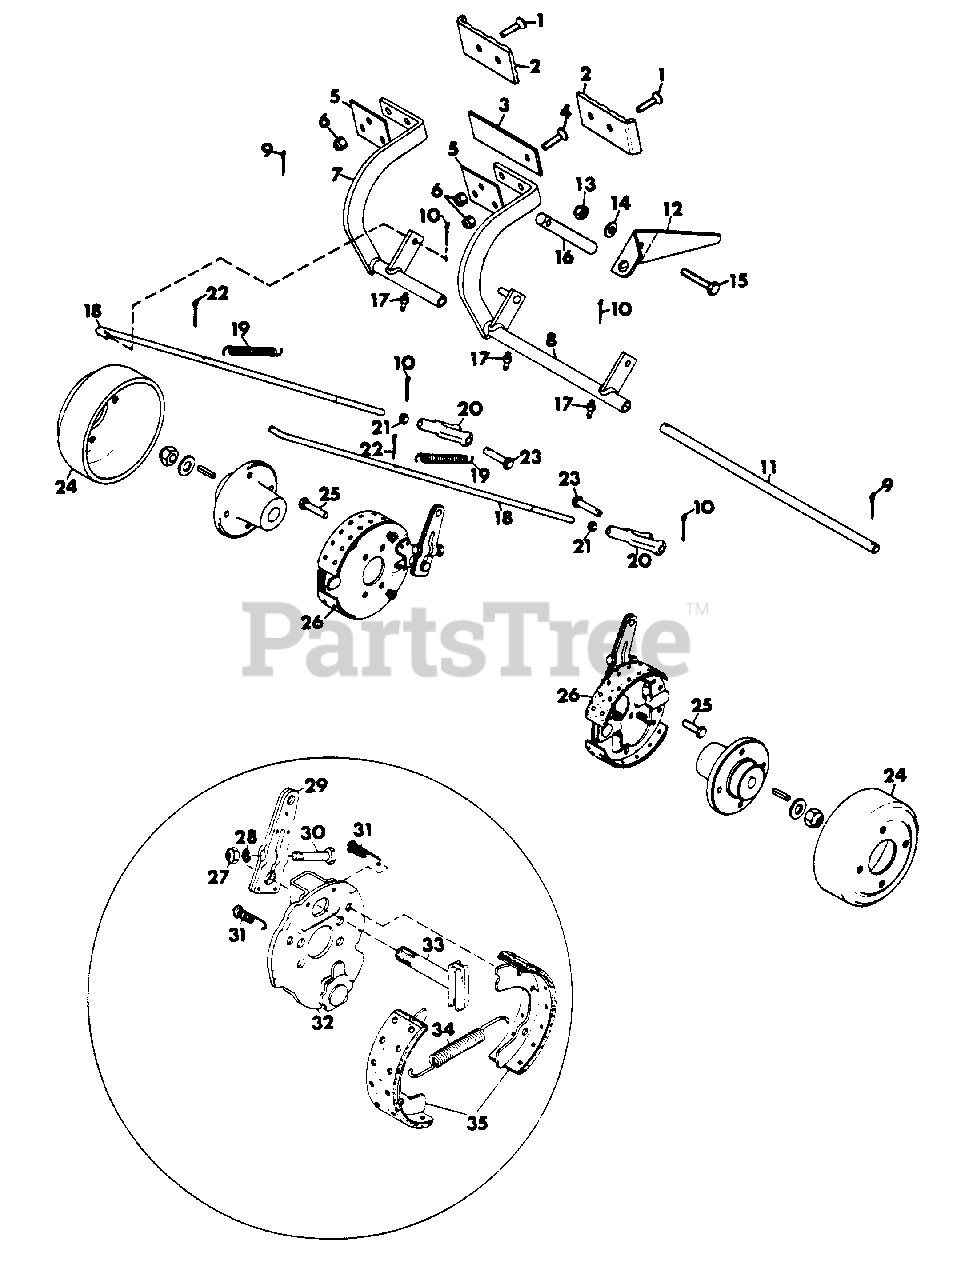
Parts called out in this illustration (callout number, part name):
1	SCREW, MACH. 1/4-20X1.25
2	PEDAL, BRAKE
3	ARM, BRAKE LOCK
4	SCREW, MACHINE 1/4-20X1.00
5	PLATE, BRAKE LOCK BACKING
6	NUT, LOCK 1/4-20
7	PEDAL, BRAKE R.H.
8	PEDAL, BRAKE L.H.
9	PIN, COTTER .125X1.25
10	PIN, COTTER .09X.75
11	SHAFT, BRAKE
12	LEVER, BRAKE LOCK
13	NUT, LOCK 3/8-16
14	WASHER, NYLON .375X.75X.060
15	BOLT, HEX 3/8-16X2.25
16	ROD
17	FITTING, LUBE 1/4-28
18	ROD, BRAKE
19	SPRING, EXT. 5.50X.50X20 RATE
20	CLEVIS, 3/8-24 ADJUSTABLE
21	NUT, JAM 3/8-24
22	PIN, COTTER .125X.750
23	PIN, CLEVIS .375X.948
24	DRUM, 7X1.75
25	BOLT, HEX 3/8-16X.75
26	BRAKE, 7X1.75
27	NUT, HEX 5/16-24
28	WASHER, LOCK 5/16
29	ARM, CAM LEVER
30	BOLT, HEX 5/16-24X1.75
31	SPRING, SHOE RETAINING
32	PLATE, BACK
33	CAM, BRAKE
34	SPRING, SHOE RETURN
35	KIT, BRAKE SHOE
